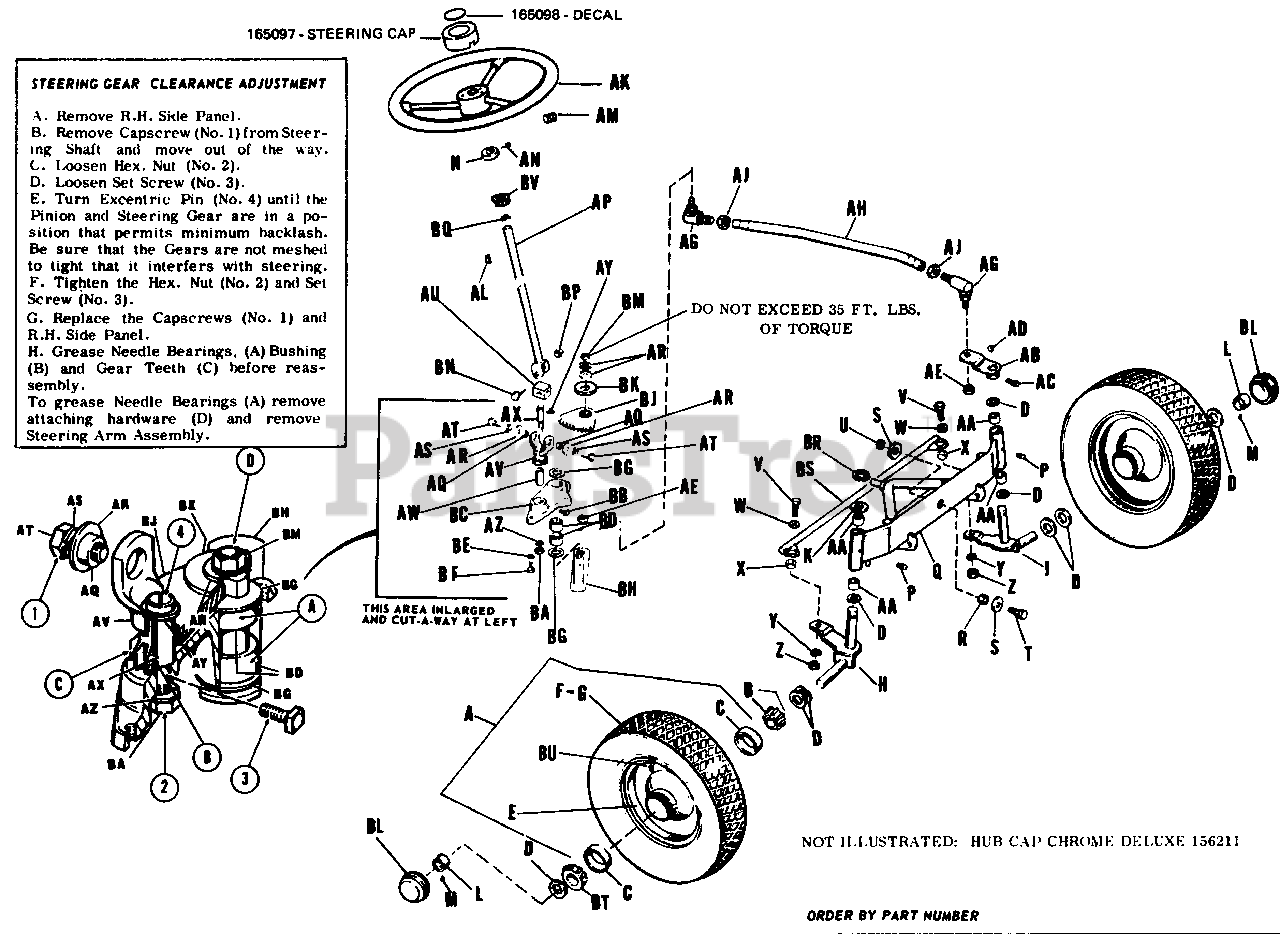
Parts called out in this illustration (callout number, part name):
A	Wheel and Tire Assembly
B	Bearing Cone w/seal
C	Bearing Cup
E	Wheel w/Bearing Cup
H	Spindle Assembly, R.H.
J	Spindle Assembly, L.H.
L	Set Collar
M	Cup Point Socket Head Set Screw, 5/16"-18 x 5/16" Lg.
N	Set Collar
P	Grease Fitting
Q	Axle Assembly, Front
S	Plain Washer, 1/2"
T	Hex. Cap Screw, 1/2"-13 x 1" Lg.
U	Full Lock Hex. Nut, 1/2"-13
V	Hex. Cap Screw, 3/8"-16 x 1 1/4" Lg.
W	Plain Washer, 3/8"
Y	Lock Washer, 3/8"
Z	Full Hex. Nut, 3/8"-16
AB	Arm Assembly, Steering, L.H.
AC	Screw, Set Cup Point, Square Head, 5/16"-18 x 1/2" Lg.
AE	Full Hex. Lock Nut, 1/2"-20
AJ	Nut, 1/2"-20 N.F.
AK	Steering Wheel
AL	Woodruff Key No. 9
AM	Socket Head Cup Point Set Screw, 5/16"-18 x 5/16" Lg.
AN	Socket Head Set Screw, 5/16"-18 x 1/4" Lg.
AP	Steering Shaft Assembly
AR	Plain Washer, 3/8"
AS	Lock Washer, 3/8"
AT	Hex. Cap Screw, 3/8"-16 x 3/4" Lg.
AU	Universal Joint Pin
AV	Bushing Assembly
AX	Pin Eccentric
AY	Retainer Ring
AZ	Lock Wasner
BA	Full Hex. Nut, 3/8"-16
BB	Sq. Hd. Set Screw, 1/4"-20 x 3/4"
BC	Steering Bracket
BD	Needle Bearing
BE	Lock Washer, 5/16"
BF	Hex. Cap Screw, 5/16"-18 x 5/8"
BH	Steering Arm Assembly
BJ	Gear Steering
BK	Arbor Washer
BL	Hub Cap
BM	Gripco Center Lock 7/16"-14
BN	Hex Cap Screw
BP	Full Hex. Nut, 5/16"-18
BR	Retaining Ring
BS	Drag Link
BT	Outside Bearing
BU	Valve Stem
BV	Steering Bushing
